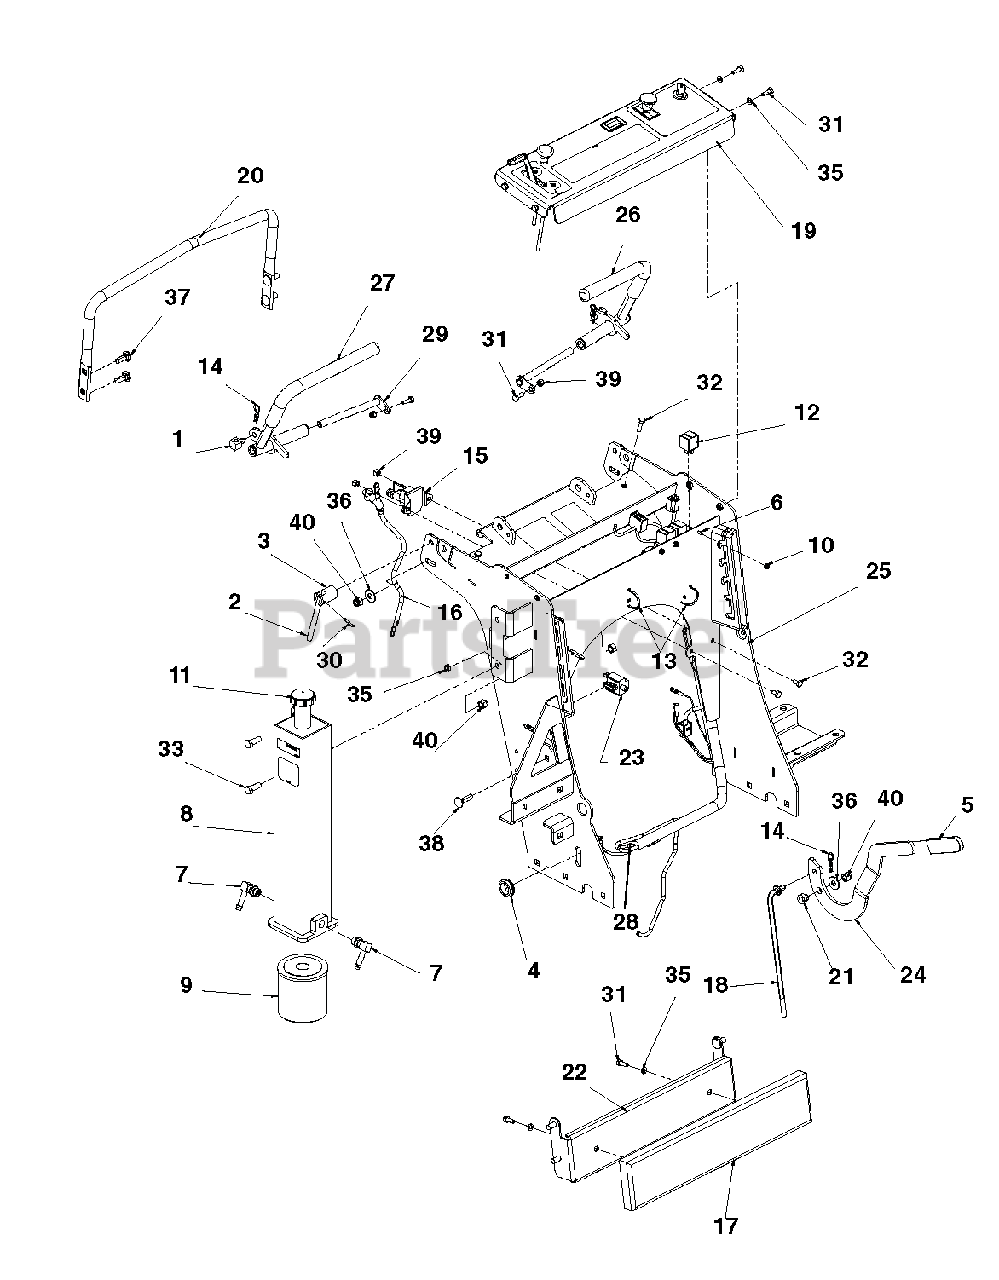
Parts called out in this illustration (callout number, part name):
1	SWIVEL ADJUSTER-THREAD SIZE 5/
2	LEVER, LOCK Y
3	BASE, LOCK LEVER Y
4	GROMMET:RUB:.88IDX1.38ODX.14GR
5	GRIP, PVC .250 X 1.00 X 3.63
6	SCREW,8-32X1/2
7	FTG, 90 9/16MOR X 3/8HOSE
8	RESERVOIR, HYDRAULIC
9	FILTER, OIL
10	#8.32 ELASTIC STOP NUT
11	CAP, FILLER, OIL
12	RELAY, ISO MINI ELEC.
13	CABLE TIE, .15 X 8.50
14	PIN, HAR .091X1.63 5/16-1/2 Y
15	SOLENOID
16	CABLE, 12" STARTER
17	PAD, THIGH
18	LINK, BRAKE Y
19	CONTROL PANEL W/DECALS GDANE
20	SUPPORT, HANDLE PAINTED
21	BUSHING, BRAKE PIVOT Y
22	WLDT, THIGH PAD BRACKET
23	SWITCH, NO-NO-NC GREY PLUNGER
24	BRAKE LEVER, OFFSET
25	WLDT, CONSOLE 34 W/DECALS YELW
26	RH CONTROL LEVER W/GRIP
27	LH CONTROL LEVER W/GRIP
28	HARNESS, WIRING
29	WLDT, PIN AND LOCK Y
30	PIN, SPRING
31	BOLT, 1/4-20X.750 HEX 5 Y
32	BOLT, 1/4-20X1.00 HEX 5 Y
33	BOLT, 3/8-16X1.00 HEX 5 Y
34	NUT, 1/4-20 STD HEX GR5 Y
35	WASHER, .250 MED SPRG LOCK Y
36	WASHER, .375 REG FLAT Y
37	BOLT, 3/8-16X1.00 CRG 5 Y
38	BOLT, 3/8-16X1.25 CRG 5 Y
39	LOCKNUT, 1/4-20 WHIZ Y
40	LOCKNUT, 3/8-16 NYLOC Y
